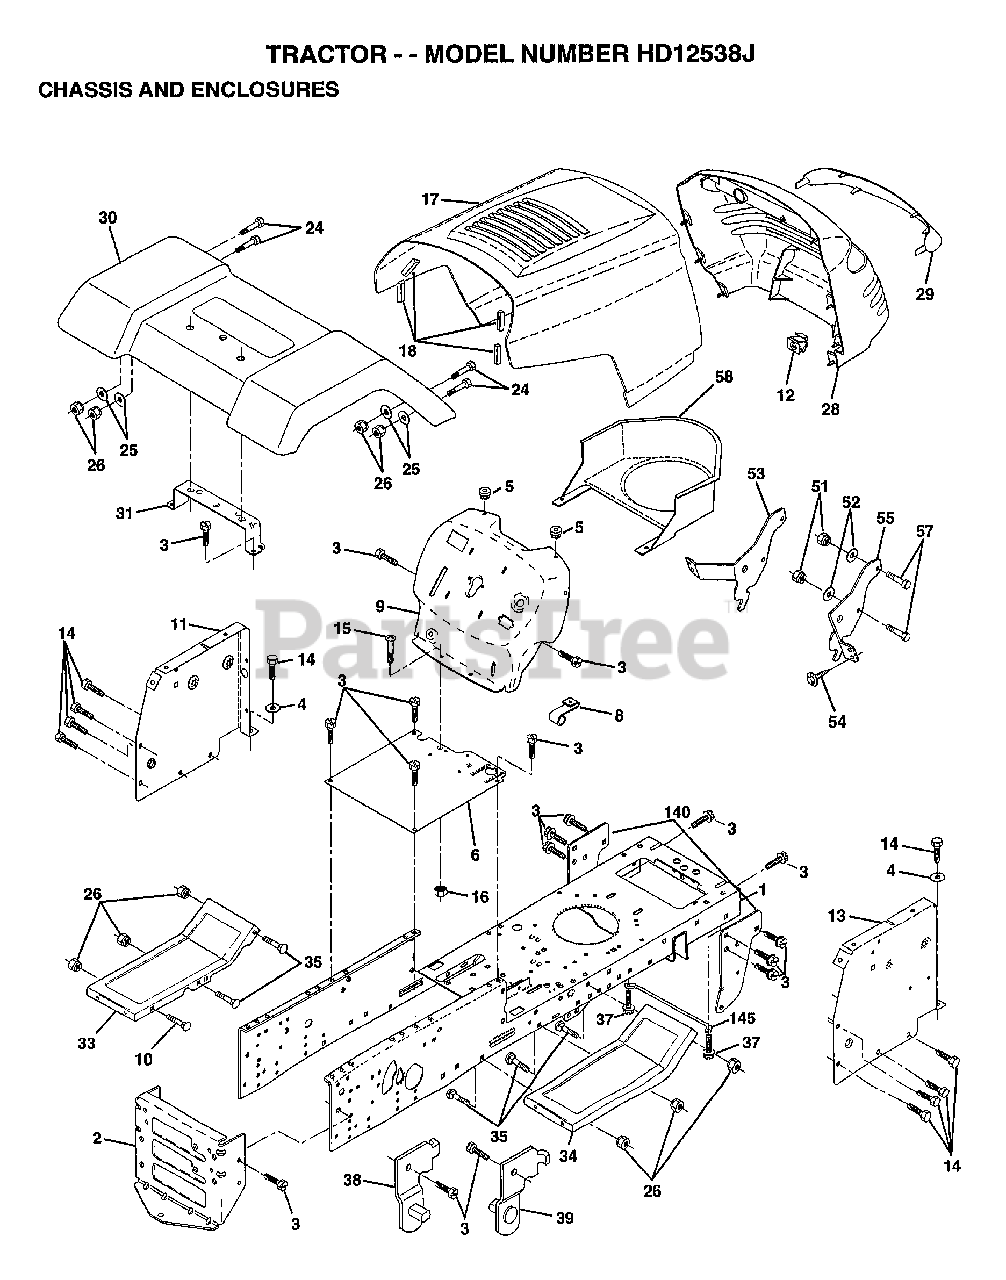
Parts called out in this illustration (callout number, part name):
1	CHASSIS.STAMPING
3	SCREW
4	WASHER
5	BUMPER-HOOD/DASH
6	SADDLE-SILKSCREEN
8	CLIP.RETAINER
9	DASH SILKSCREEN
11	"PANEL-DASH,LH"
12	CLIP.TINNERMAN
14	SCREW LT
15	SCREW
17	HOOD.STEEL.ASSY
24	BOLT
25	WASHER
26	NUT
28	GRILLE
29	LENS.GRILLE
30	FENDER PNT LT
31	BRKT FENDER
33	FOOTREST.LH.PERF.
34	FOOTREST.RH.PERF.
35	BOLT
37	SCREW LT
38	BRACKET ASM LH
39	BRACKET ASM RH
51	NUT
52	WASHER
53	BRACKET.GRILLE.LH
54	SCREW.HEX.WS.HD
55	BRACKET.GRILLE.RH
58	AIR DUCT
140	BRKT SUSPENSION
145	"ROD POVOT,CHASSIS"
